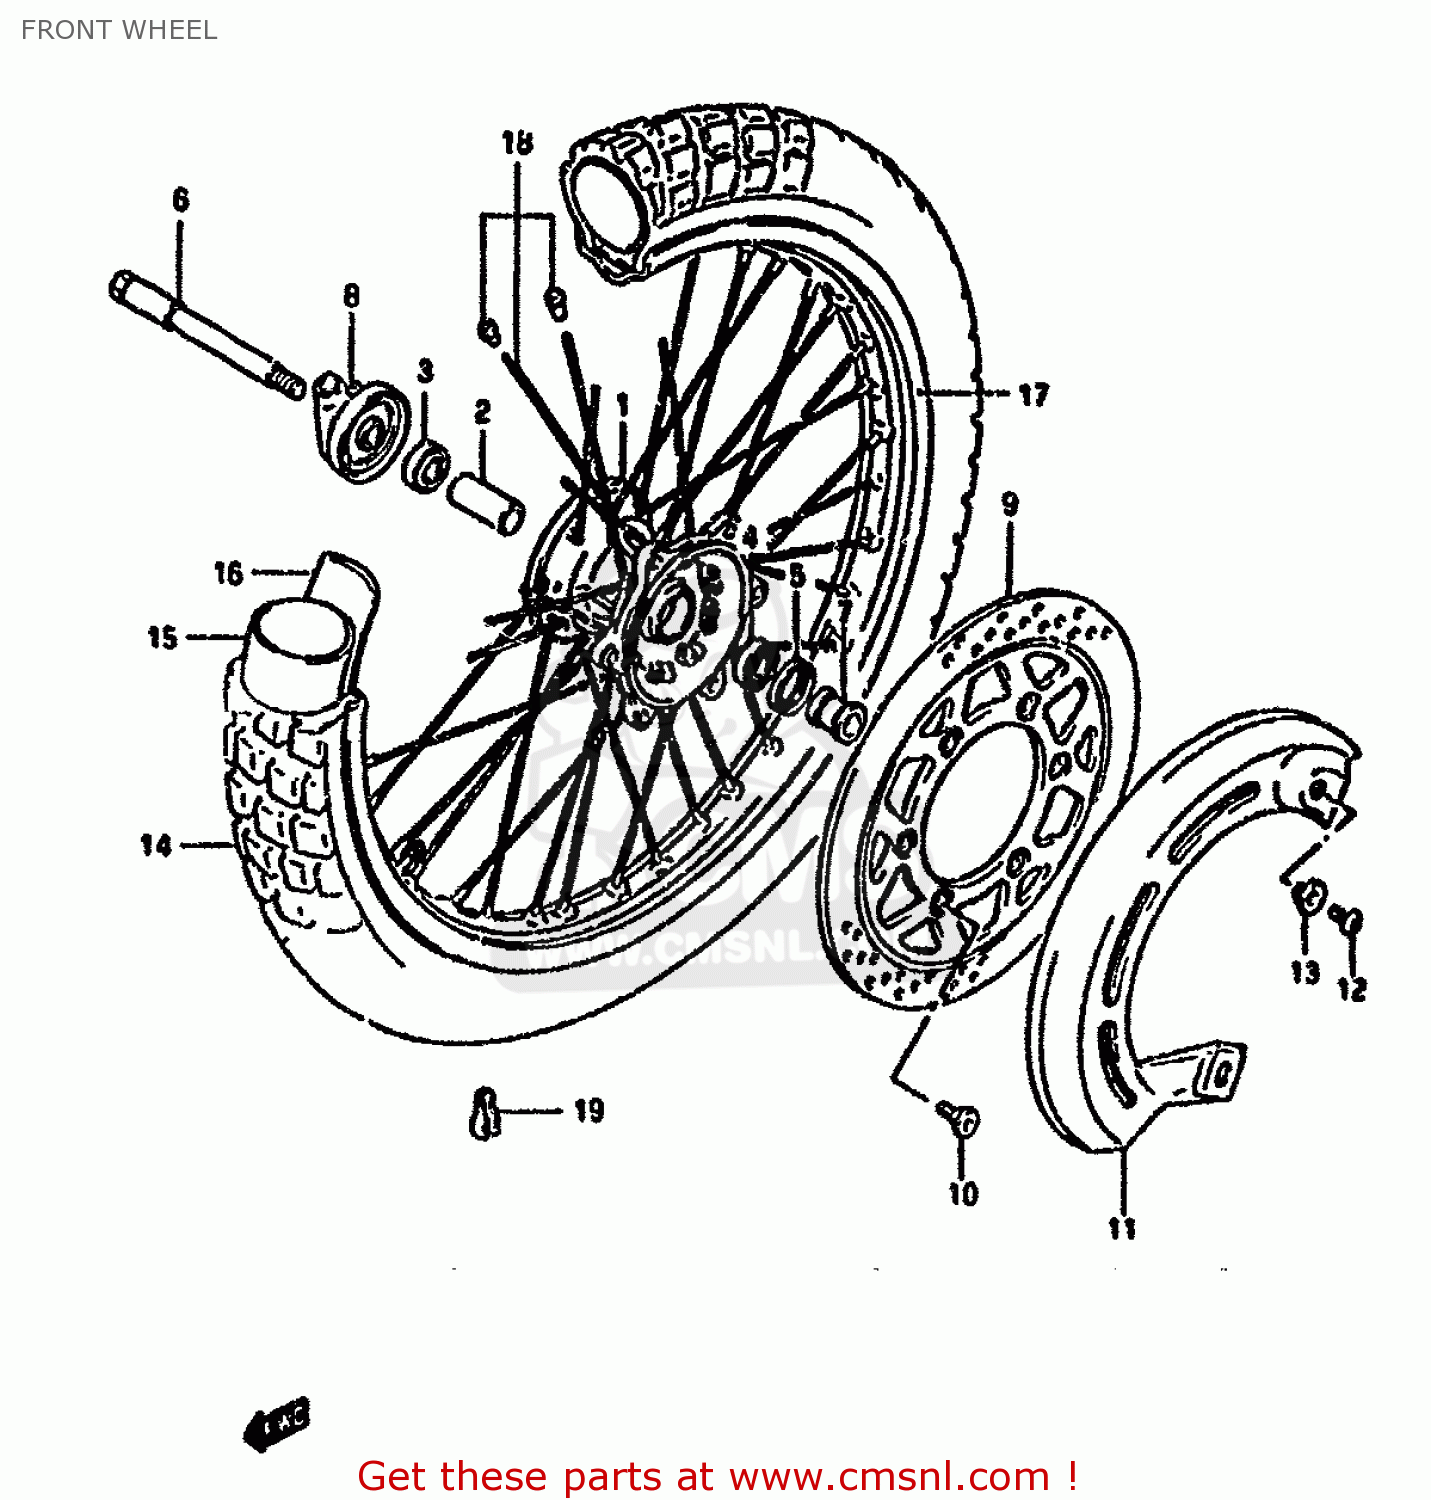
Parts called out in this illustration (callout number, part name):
1	HUB,FRONT WHEEL
2	SPACER,FR HUB BEARING
3	BEARING
4	BEARING
5	SEAL,HUB LH
6	AXLE,FR
7	SPACER,FR AXLE,L
8	BOX ASSY,SPEEDOMETER GEAR
9	DISC,FR BRAKE
10	BOLT,BRAKE DISC
11	COVER,FRONT BRAKE DISC
12	SCREW 6X12
13	WASHER
14	TIRE,FRONT 90/90-21 54
15	TUBE,INNER
16	PROTECTOR,WHEEL,INNER
17	RIM,FR WHEEL(21X1.85)
18	SPOKE SET,FR WHEEL
19	BALANCER,WHEEL
